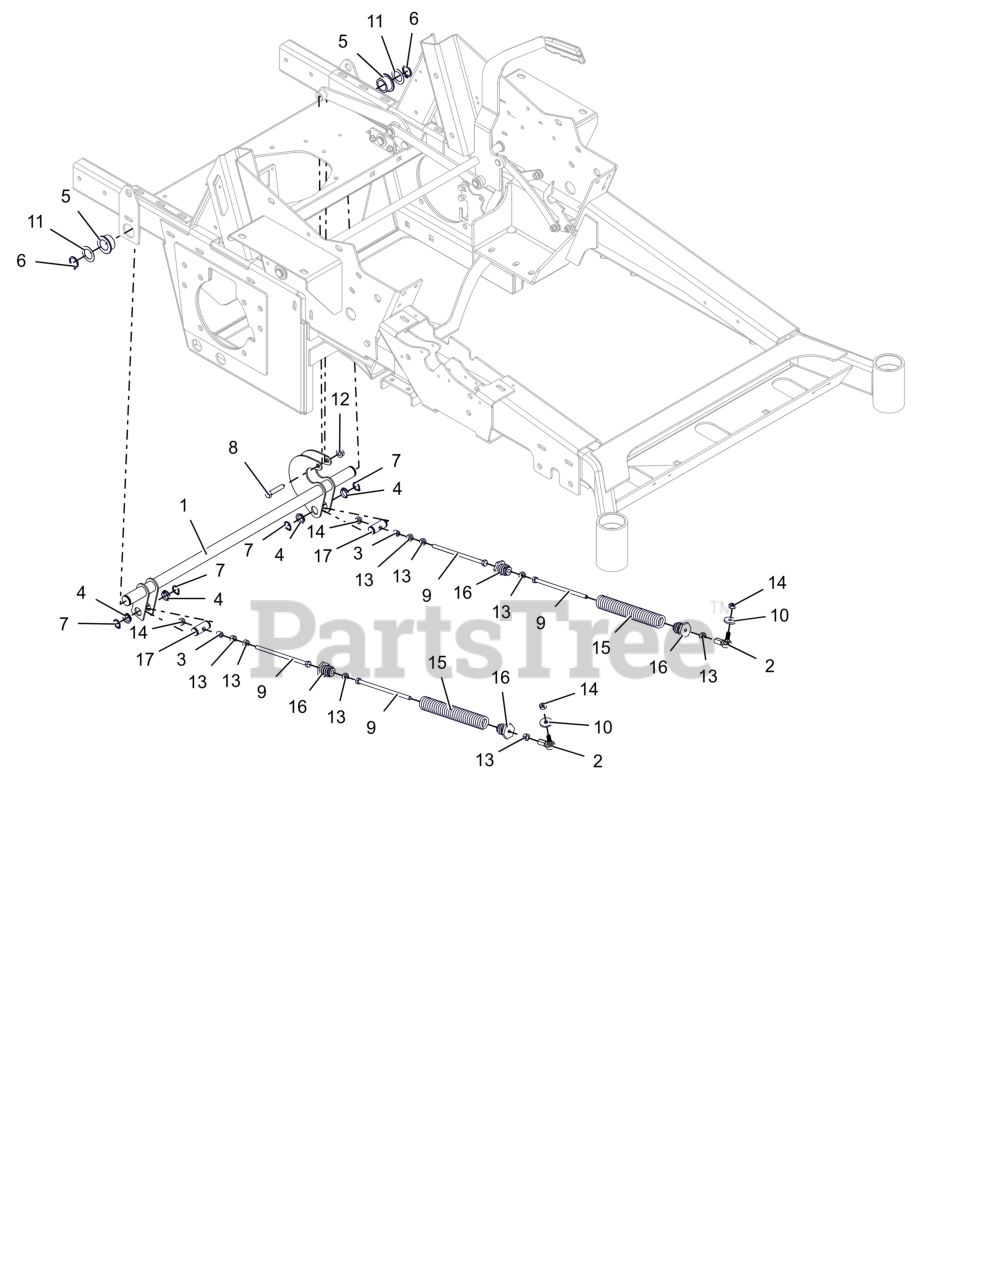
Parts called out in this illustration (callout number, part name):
1	WLDMT, BRAKE REAR PIVOT SHAFT
2	LINKAGE, BALL JOINT .312-24 UNF RH STUD
3	SPACER .50 X .32 X .42
4	BSHG, POLYLINER- .75 SNAP-IN
5	BSHG-FLG1.020X1.385X.75X1.75NY
6	RG-RTNG-EXT 1.00X.078
7	RG-RTNG-EXT .689X.078
8	BLT, HEX .38-16X1.75F G5 ZCC
9	BLT-HEX.31-24X6.5 FULTHD G5ZCC
10	WSHR, FLT .340X1.125X.135 ZCC
11	WSHR-HDND-THRUST 1.00X1.55X.03
12	NUT-LK-CTR-FLG .375-16 GF ZCC
13	NUT, HEX-JAM .3125-24 ZCC
14	NUT-CTRLK .31-24 YWZC
15	SPRG, EXTENSION .063 X .653 X 2.755
16	PLUG, SPRG
17	TRUNNION, BRAKE PIVOT
